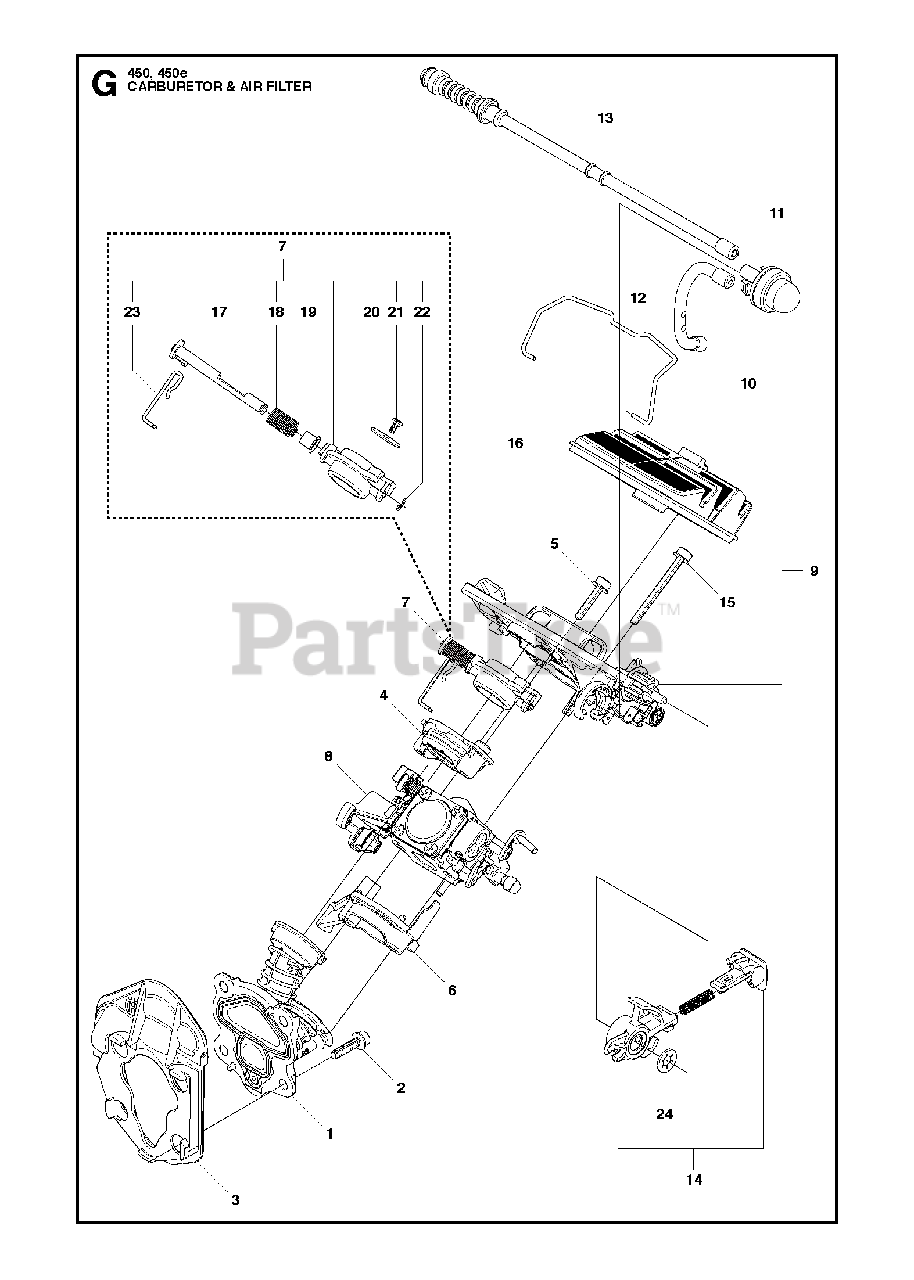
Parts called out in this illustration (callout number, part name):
1	INLET PIPE ASSY
3	INTERMEDIATE WALL
8	CARBURETOR
9	%FILTER HOLDER
10	SHACKLE
11	AIR PURGE BUBBLE
12	HOSE
13	RP RETURN HOSE
16	AIR FILTER - NYLON (80)
16	AIR FILTER - NYLON (44)
16	AIR FILTER - FELT
17	SHAFT ASSY
18	SPRING
19	COLLAR
20	VALVE
21	SCREW
22	CLIP
23	ROD
24	LOCK WASHER
